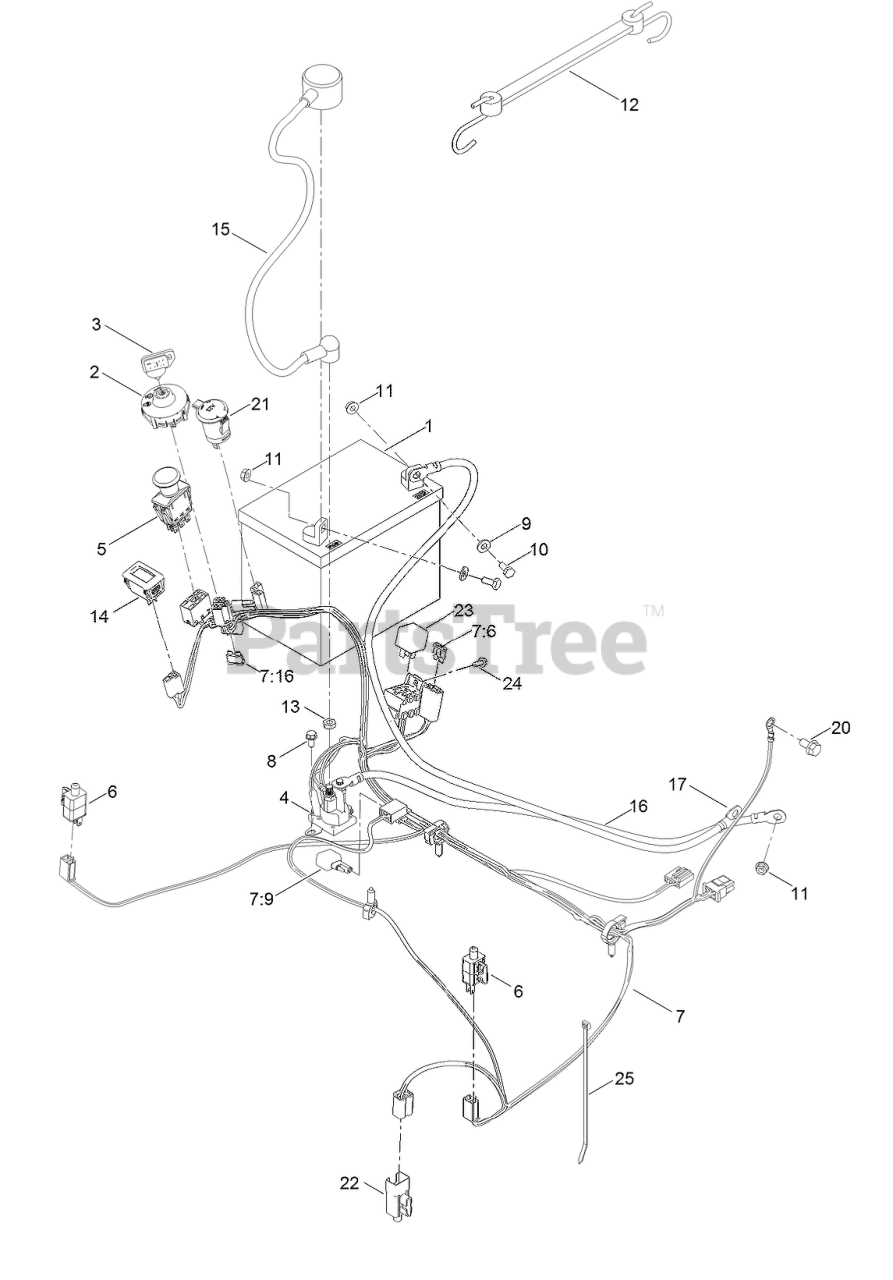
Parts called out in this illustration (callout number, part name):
1	BATTERY
2	SWITCH-IGNITION
3	KEY-IGNITION
4	SOLENOID
5	SWITCH-PTO
6	SWITCH
7	HARNESS-WIRE
7:6	FUSE-BLADE, 25 AMP
7:16	FUSE-BLADE, 15 AMP
8	SCREW-HWH
9	WASHER-FLAT
10	SCREW-HH
11	NUT-HF
12	HOLDDOWN-BATTERY
13	NUT-JAM
14	HOURMETER
15	CABLE-BATTERY, POSITIVE
16	CABLE-BATTERY, POSITIVE
17	CABLE-BATTERY, NEGATIVE
20	SCREW-HHF
21	PORT-POWER, 12V
22	SWITCH-REVERSE
23	RELAY
24	SCREW-TAPTITE
25	TIE-CABLE
